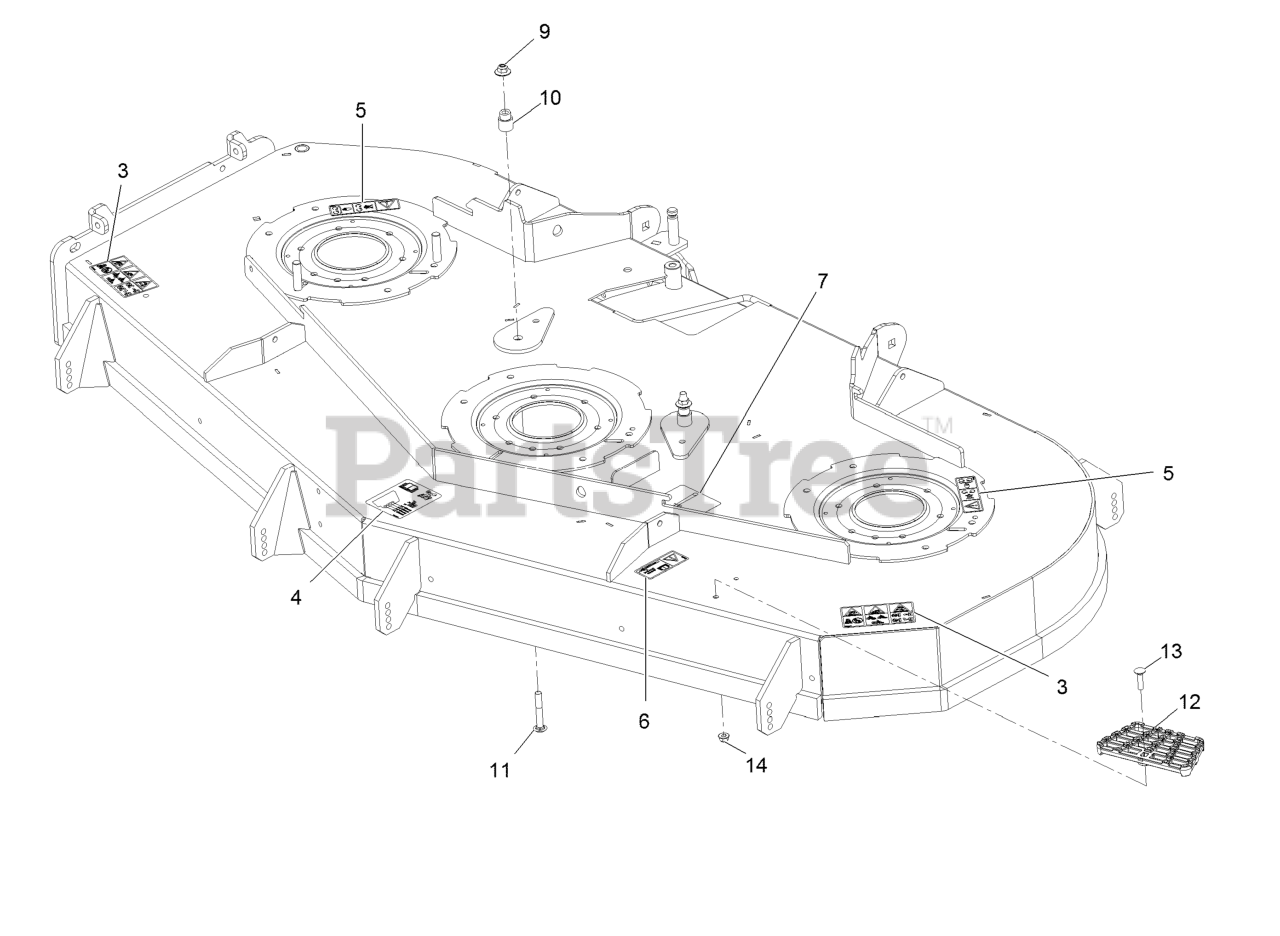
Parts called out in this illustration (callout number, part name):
3	Decal-Danger Thrown Objects
4	Decal-Roller, Anti-Scalp
5	Decal-Missing, Cover
6	Decal-Bolt Torque
7	Decal-Belt Routing
9	Nut-Flange, NI
10	Bushing, Idler
11	Screw-CARR
12	Step-Deck
13	Screw-CARR
14	Nut-HF, NI
